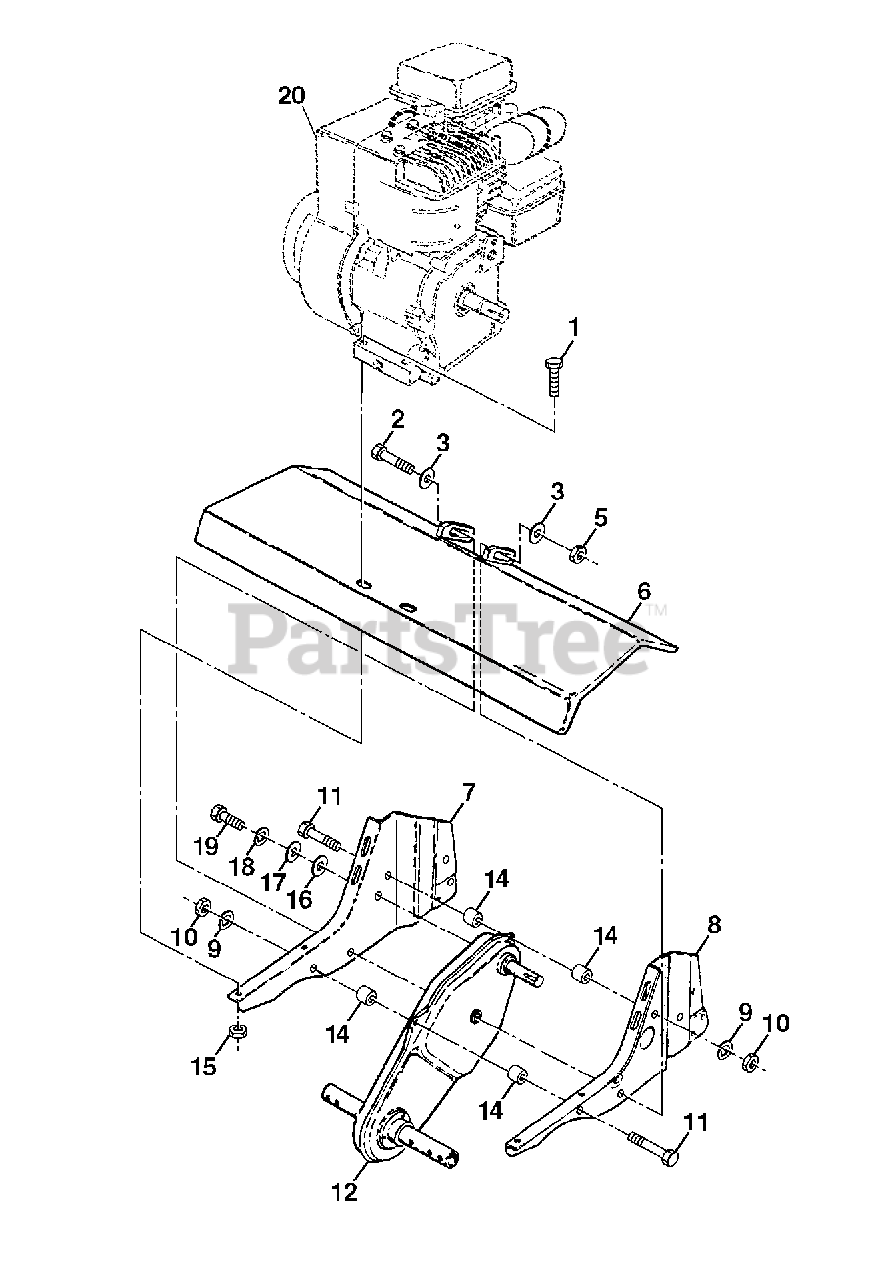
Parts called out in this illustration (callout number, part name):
1	Bolt, Hex 5/16-18 x 1-1/2 Gr. 2
2	Bolt, Hex, Fin 3/8-16 x 3-1/4
3	Washer 13/32 x 13/16 x 11
5	Locknut, Hex, w/washer 3/8-16
6	Shield, Tine
7	Bracket, Engine, R.H.
8	Bracket, Engine, L.H.
9	Washer, Lock 5/16
10	Nut, Hex 5/16-18
11	Bolt, Hex 5/16-18 x 2-3/4
12	Transmission
14	Spacer, Split
15	Nut, Keps 5/16
16	Washer 9/32 x 7/8 x 12 Ga.
17	Washer 9/32 x 1-1/4 x 16 Ga.
18	Washer, Lock 1/4
19	Bolt, Hex 1/4-28 x 3/4 Gr. 5
